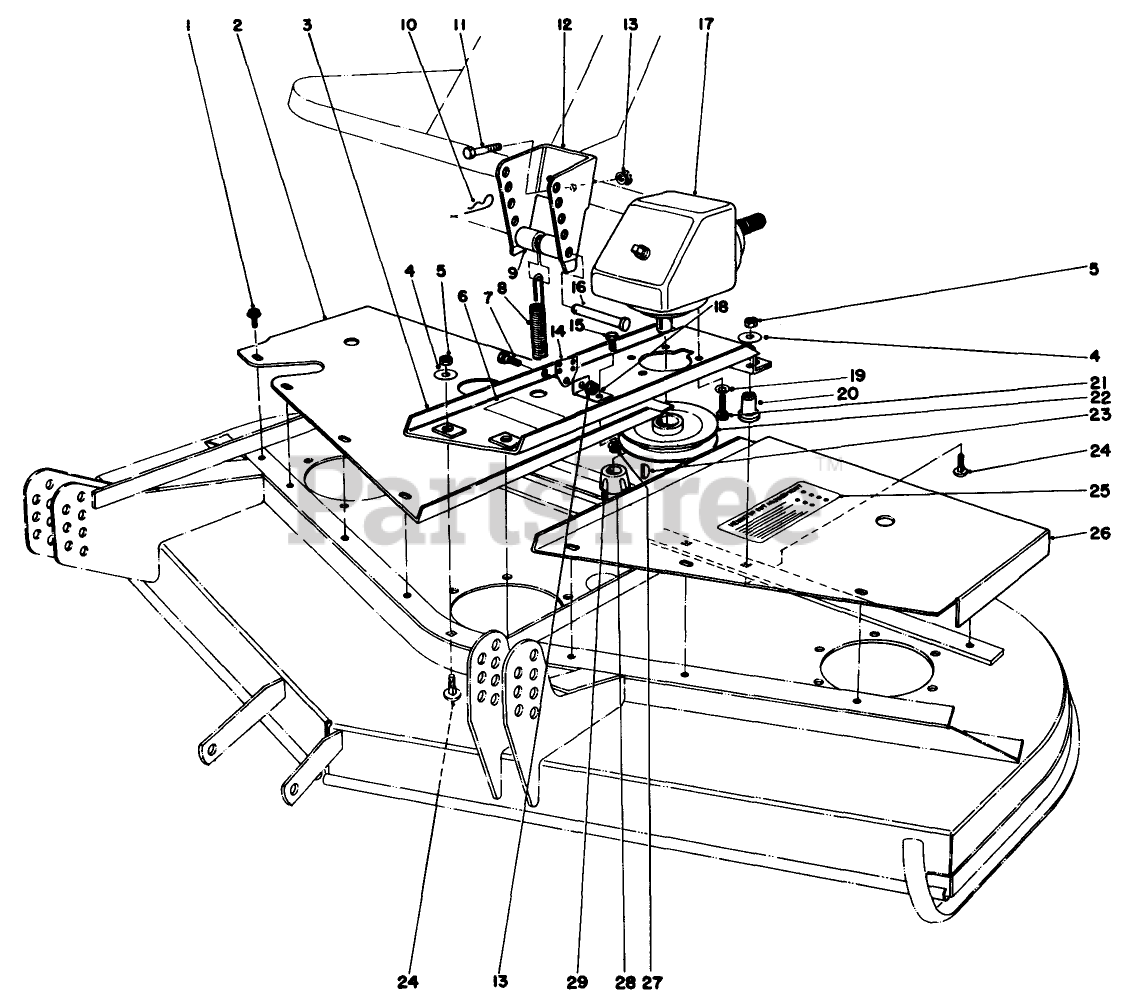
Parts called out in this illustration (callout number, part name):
1	SCREW-HHFTF
2	RH COVER WA *R
4	WASHER
5	NUT-HEX
7	BOLT-SHOULDER
9	SPACER
10	PIN-HAIR
11	SCREW-HH
12	SPRING BRACKET *R
13	NUT-HHF, WHIZ
15	SCREW-HH
16	PIN-CLEVIS
18	EXTENSION BRKT *R
19	WASHER-LOCK
20	MOUNT
21	SCREW-HSH
22	GEARBOX PULLEY ASM
23	KEY-WOODRUFF
24	SCREW-CARR
26	LH COVER WA *R
27	NUT-HF
28	BUSHING-LOCK, TAPER
29	SCREW-SET, HSH
